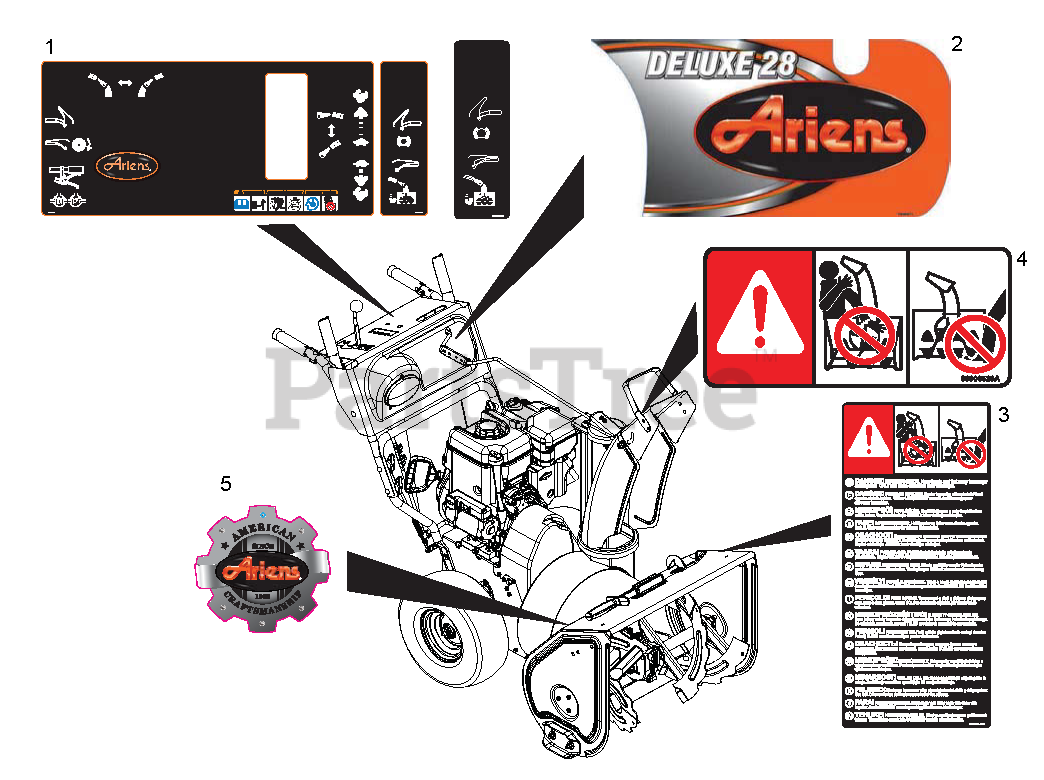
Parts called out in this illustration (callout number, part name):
1	DECAL,CTRL CRNK,REMOTE,CLICKER
2	DECAL, DELUXE 28
3	DECAL, DANGER - ROTATING PARTS
4	DECAL, DANGER
5	Decal, Ariens Heritage
